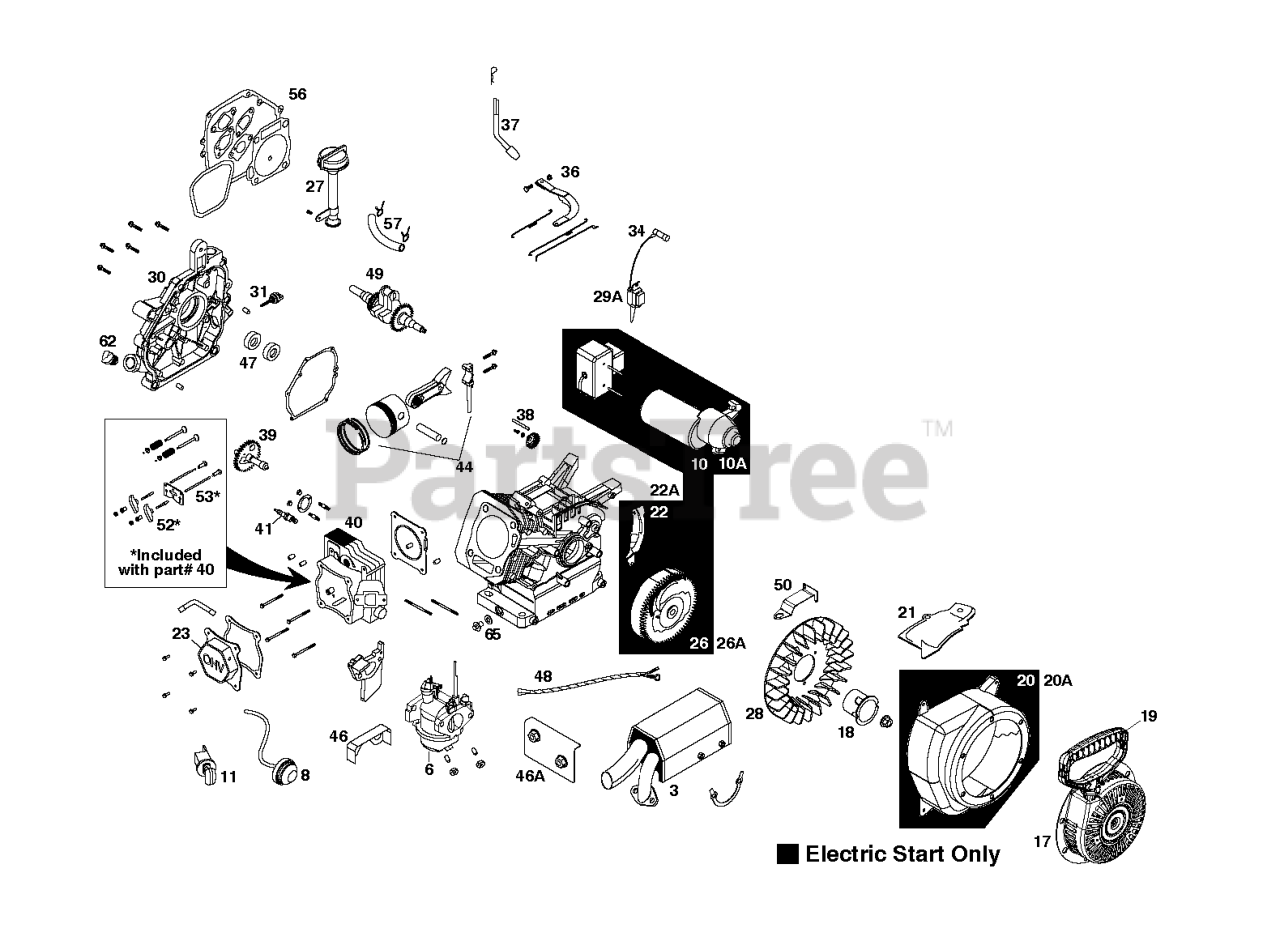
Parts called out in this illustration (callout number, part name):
3	MUFFLER.ASM.LCT.208CC.SNGL.STG
6	CARB.GEN2.W/O.SPACER.LCT.208CC
8	BULB.FUEL.PRMR.W/HOSE(SKSNO306
10	STARTER.ASM.ELEC.(SKSNO411)
10A	STARTER STARTER.EURO
11	SWITH.KEY.ASSEM.SNOW.SINGLE.ST
17	RECOIL.STRT.ROUND(BLK) SNOW
18	STRTER.CUP(NON-SLOT)SKSN0601.2
19	STARTER.GRIP.SNOW.LCT.SKSN0603
20	BLOW.HSG.ASSY.ELEC(SKSN-0602)
20A	BLOW.HSG.ASSY.ELEC(SKSN-0612)
21	SHIELD.CYLINGER.LCT.SKSN0608.1
22	SHLD.ELEC.START.FLY(SKSN-0605)
22A	SHIELD.FLYWEEL.MAN(SKSN-0607)
23	VALVE COVER ASSEMBLY
26	FLYWHL.ASSY.ELECT.(SKSN0405)
26A	RP KIT.FLYWHEEL.SERVICE
27	HIGH OIL-FILL TUBE ASSY
28	FLYWHEEL FAN 420586
29A	208CC IGN COIL (STD)
30	CRANKCASE COVER ASSY
31	DIPSTICK SMALL
34	SPARK.PLUG.BOOT.SNW,SKSN4691.1
36	RP_IT.GOVERNOR.ARM(SUMMER ENG)
37	KIT.GOVERNOR.CRANK(SK208-3100)
38	GOVENOR.GEARS ASM(SK2082900)
39	KIT.CAMSHAFT.208CC.LCT
40	CYLINDR.HEAD.SRV.KIT W/GASKET
41	SPARK.PLUG(2083810)
44	KIT.PISTON.SRV(SK208-1400)
46	SHIELD.VAPOR.SNOW
46A	SHIELD.INTAKE.(LCT.SKSN0140.1)
47	SEAL KIT (2 PCS)
48	HARNESS.WIRE/WCDI.IGN.LCT
49	CRANKSHAFT-KEYED(SK2081800.1)
50	SPEED.CTRL.BRKT.(SKSN0150)
52	ROCKER ARM KIT
53	KIT.PUSH.ROD.SRV(SK208-1001)
56	GASKET.KIT.208CC(SK2084300.1)
57	KIT.FUEL.HOSE.208CC.SING/STAGE
62	KIT.OIL.DRAIN.PLUG(SK2089911
65	KIT.OIL.DRAIN.PLUG(SK2089911
